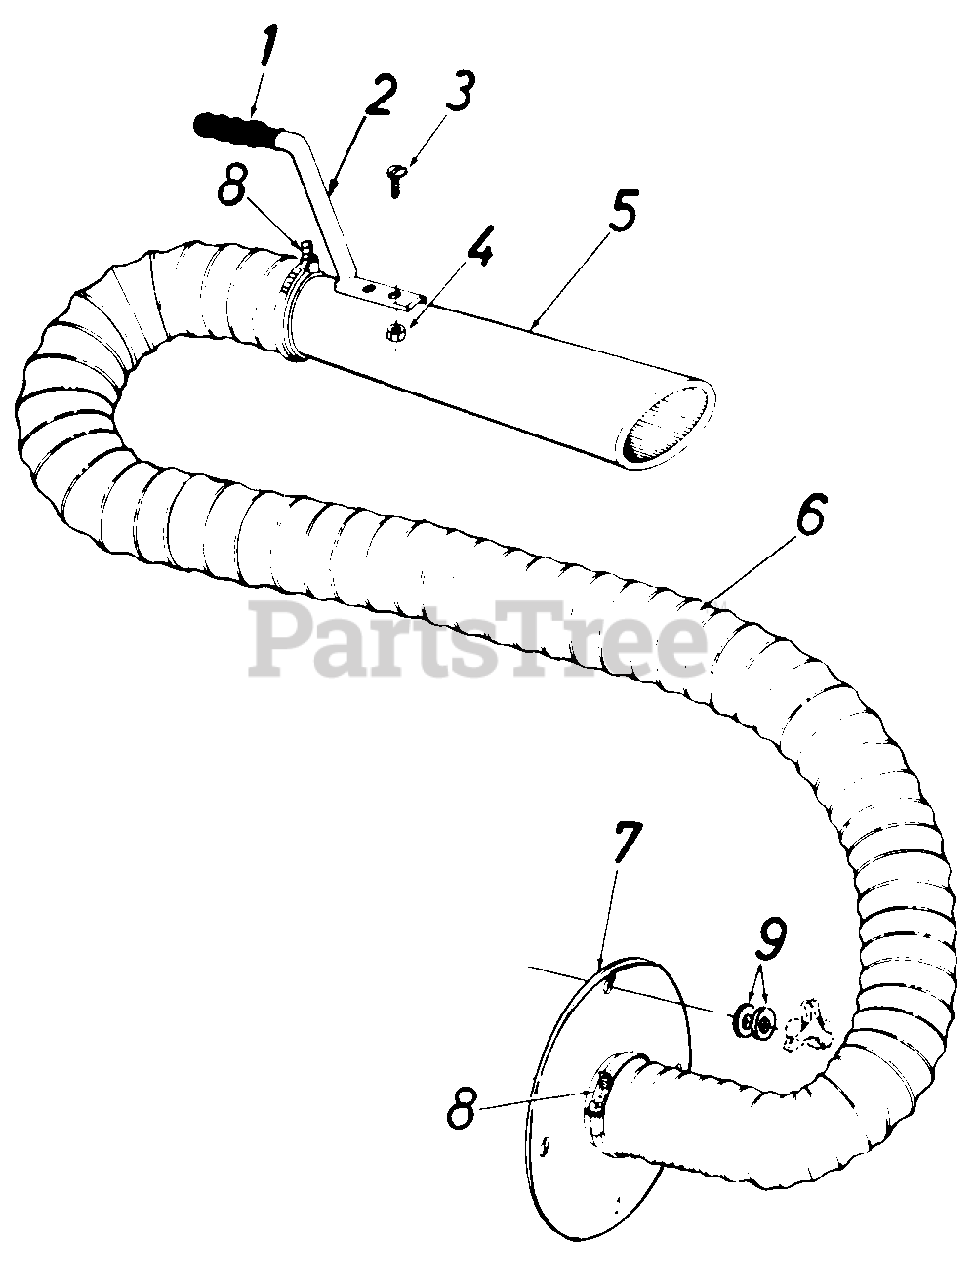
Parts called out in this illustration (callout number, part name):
1	Handle Grip
2	Handle
3	Truss Sems Scr. 10-24 x 1/2" Lg.*
4	Hex Nut 10-24 Thd.*
5	Hose Nozzle
6	Flex ible Hose 4" Dia. x 10' Lg.
9	Flat Washer .34 I.D. x 1.12 O.D.
